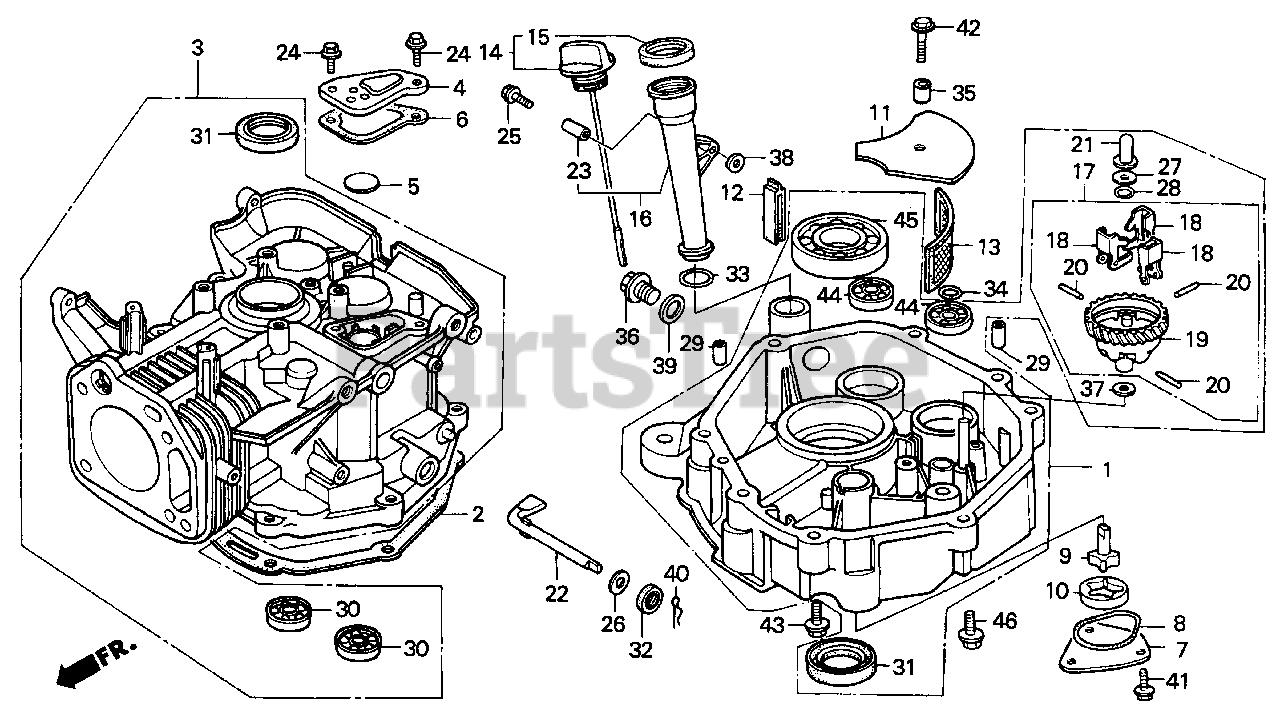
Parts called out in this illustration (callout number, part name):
1	PAN ASSY., OIL
2	GASKET, OIL PAN
3	CYLINDER ASSY.
4	CAP, BREATHER CHAMBER
5	VALVE, BREATHER
6	GASKET, BREATHER CAP
7	COVER, OIL PUMP
8	O-RING, PUMP COVER
9	ROTOR (INNER)
10	ROTOR, OIL PUMP (OUTER)
11	PLATE, OIL FILTER
12	RUBBER, OIL RETURN
13	SCREEN, OIL FILTER
14	CAP ASSY., OIL FILLER
15	GASKET, OIL FILLER CAP
16	EXTENSION, OIL FILLER
17	GOVERNOR ASSY.
18	WEIGHT, GOVERNOR
19	HOLDER, GOVERNOR WEIGHT
20	PIN, GOVERNOR WEIGHT
21	SLIDER, GOVERNOR
22	SHAFT, GOVERNOR ARM
23	COLLAR, EXTENSION
24	BOLT, FLANGE (6X12) (CT200)
25	BOLT, FLANGE (6X35)
26	WASHER, THRUST (8.1MM)
27	WASHER (6X16)
28	CLIP, GOVERNOR HOLDER
29	PIN, DOWEL (8X12)
30	BEARING, RADIAL BALL (6202)
31	OIL SEAL (35X52X8)
32	OIL SEAL (8X14X5)
33	O-RING (22.5X2.2)
34	O-RING (11.8X2.4)
35	COLLAR, OIL FILTER SETTING
36	BOLT, DRAIN PLUG (20MM)
37	WASHER, PLAIN (6MM)
38	WASHER, PLAIN (6MM)
39	WASHER, DRAIN PLUG (20MM)
40	PIN, LOCK (8MM)
40	PIN, LOCK (10MM)
41	BOLT, FLANGE (6X12)
42	BOLT, FLANGE (6X25)
43	BOLT, FLANGE (8X40)
44	BEARING, RADIAL BALL (6202)
45	BEARING, RADIAL BALL (6207)
NI	GOVERNOR KIT
